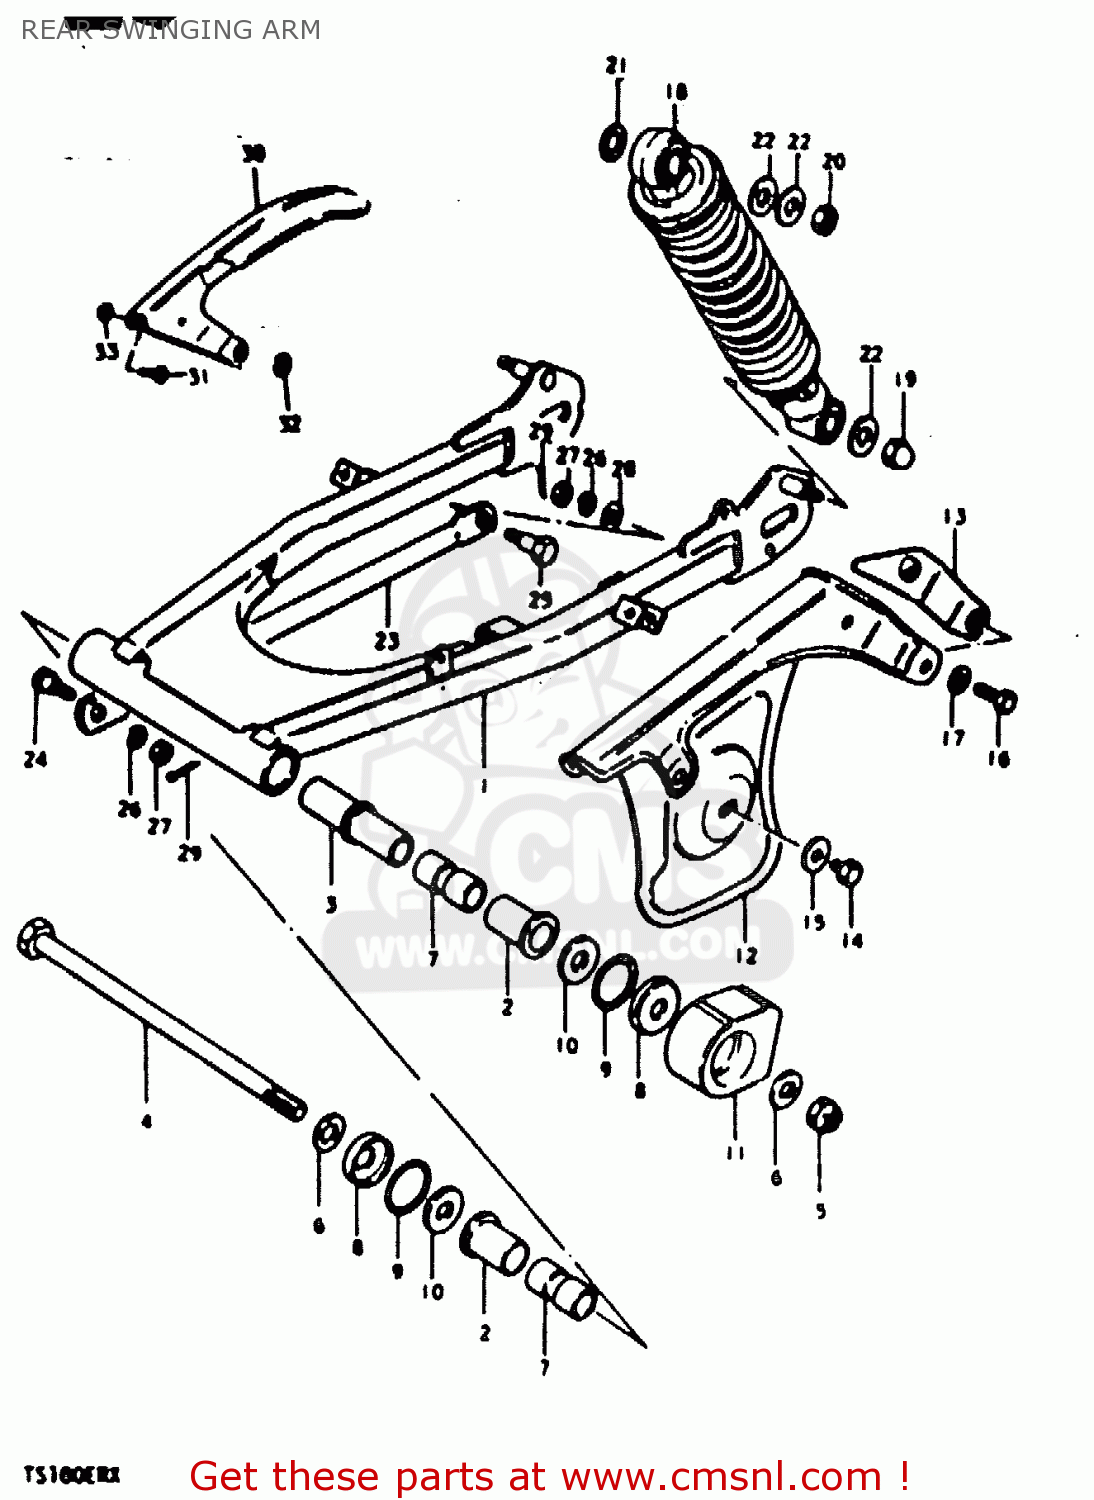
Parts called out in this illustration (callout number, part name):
1	SWINGING ARM SET
2	BUSH
3	SPACER,RR SWGARM PIVOT CTR
4	SHAFT,REAR SWING ARM
5	NUT 12MM
6	WASHER
7	SPACER,RR SWGARM PIVOT
8	COVER,SWGARM BUSH DUST SEAL
9	O RING(D:2,ID:24.5)
10	WASHER(12.5X24X2.3)
11	BUFFER,CHAIN TOUCH DEFENSE
12	CASE,CHAIN
13	REINFORCEMENT,CHAIN CASE
14	BOLT(6X8)
15	WASHER
16	BOLT, UPPER
17	WASHER
18	ABSORBER ASSEMBLY,REAR SHOCK
19	NUT, LOWER LH
20	NUT
21	WASHER
22	WASHER
23	TORQUE LINK,REAR
24	BOLT(8X22)
25	BOLT(8X26.5)
26	LOCK WASHER
27	NUT
28	WASHER
29	PIN
